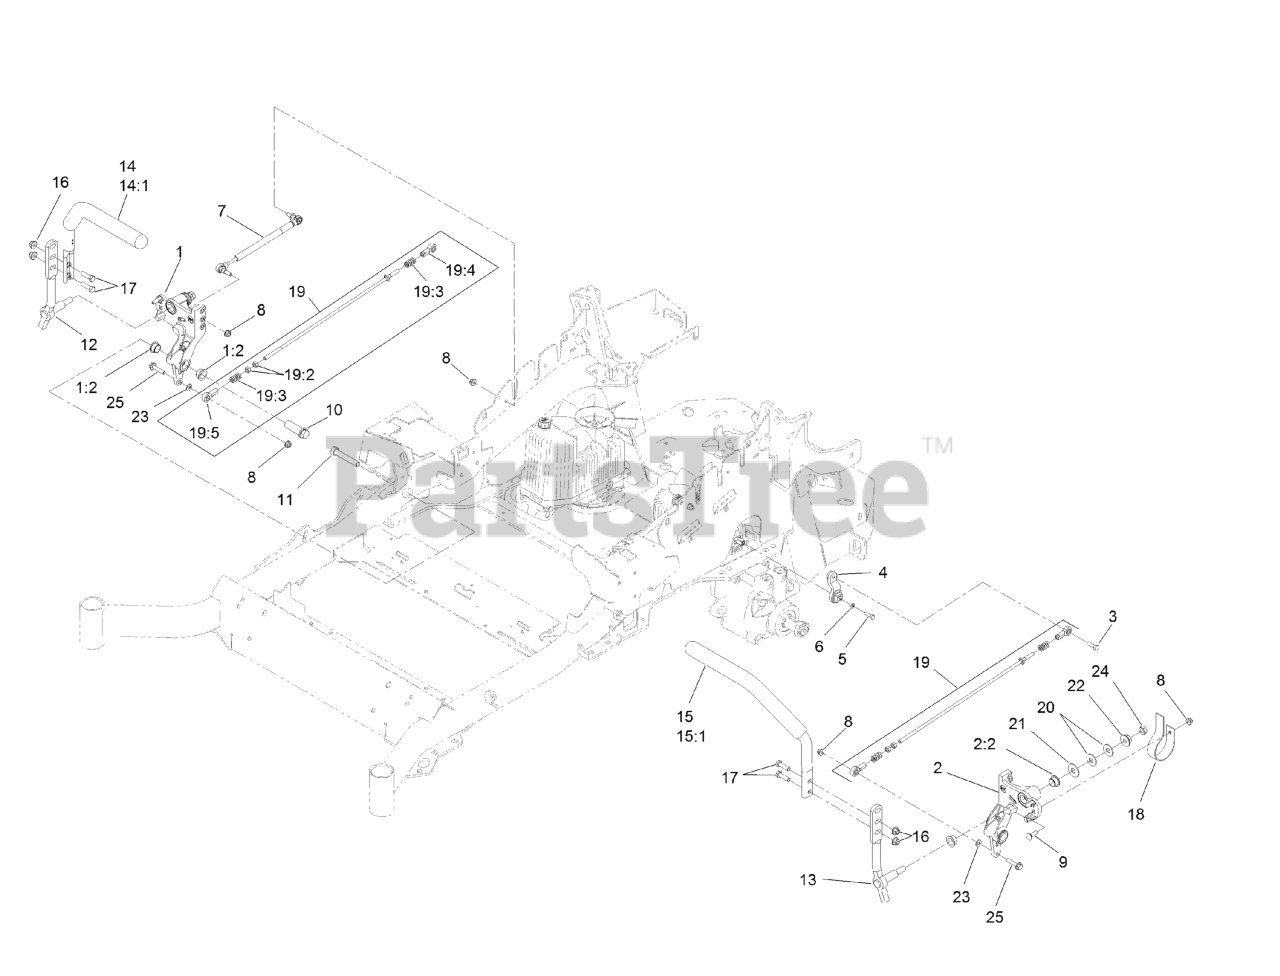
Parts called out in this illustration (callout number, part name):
1	RH MOTION CONTROL AND BUSHING ASM
1:2	BUSHING-FLANGE
2	LH MOTION CONTROL AND BUSHING ASM
2:2	BUSHING-FLANGE
3	SCREW-HH, THREAD LOCKING
4	ARM-CONTROL, PUMP
5	SCREW-HH
6	WASHER-SPRING
7	DAMPER-CONTROL, MOTION
8	NUT-HF, NI
9	BOLT-CARR
10	HUB-THREADED
11	SCREW-HH
12	LEVER-CONTROL MOTION, RH
13	LEVER-CONTROL MOTION, LH
14	RH STEERING HANDLE ASM
14:1	GRIP-LEVER, CONTROL
15	LH STEERING HANDLE ASM
15:1	GRIP-LEVER, CONTROL
16	NUT-HF, NI
17	SCREW-HH
18	SPRING-LEAF
19	FRONT PUMP LINKAGE ASM
19:2	NUT-HEX
19:3	SPRING-COMPRESSION
19:4	BALLJOINT-LH
19:5	BALLJOINT-RH
20	WASHER-SPRING
21	WASHER-FLAT
23	WASHER-PLAIN
24	NUT-JAM
25	SCREW-HHF
